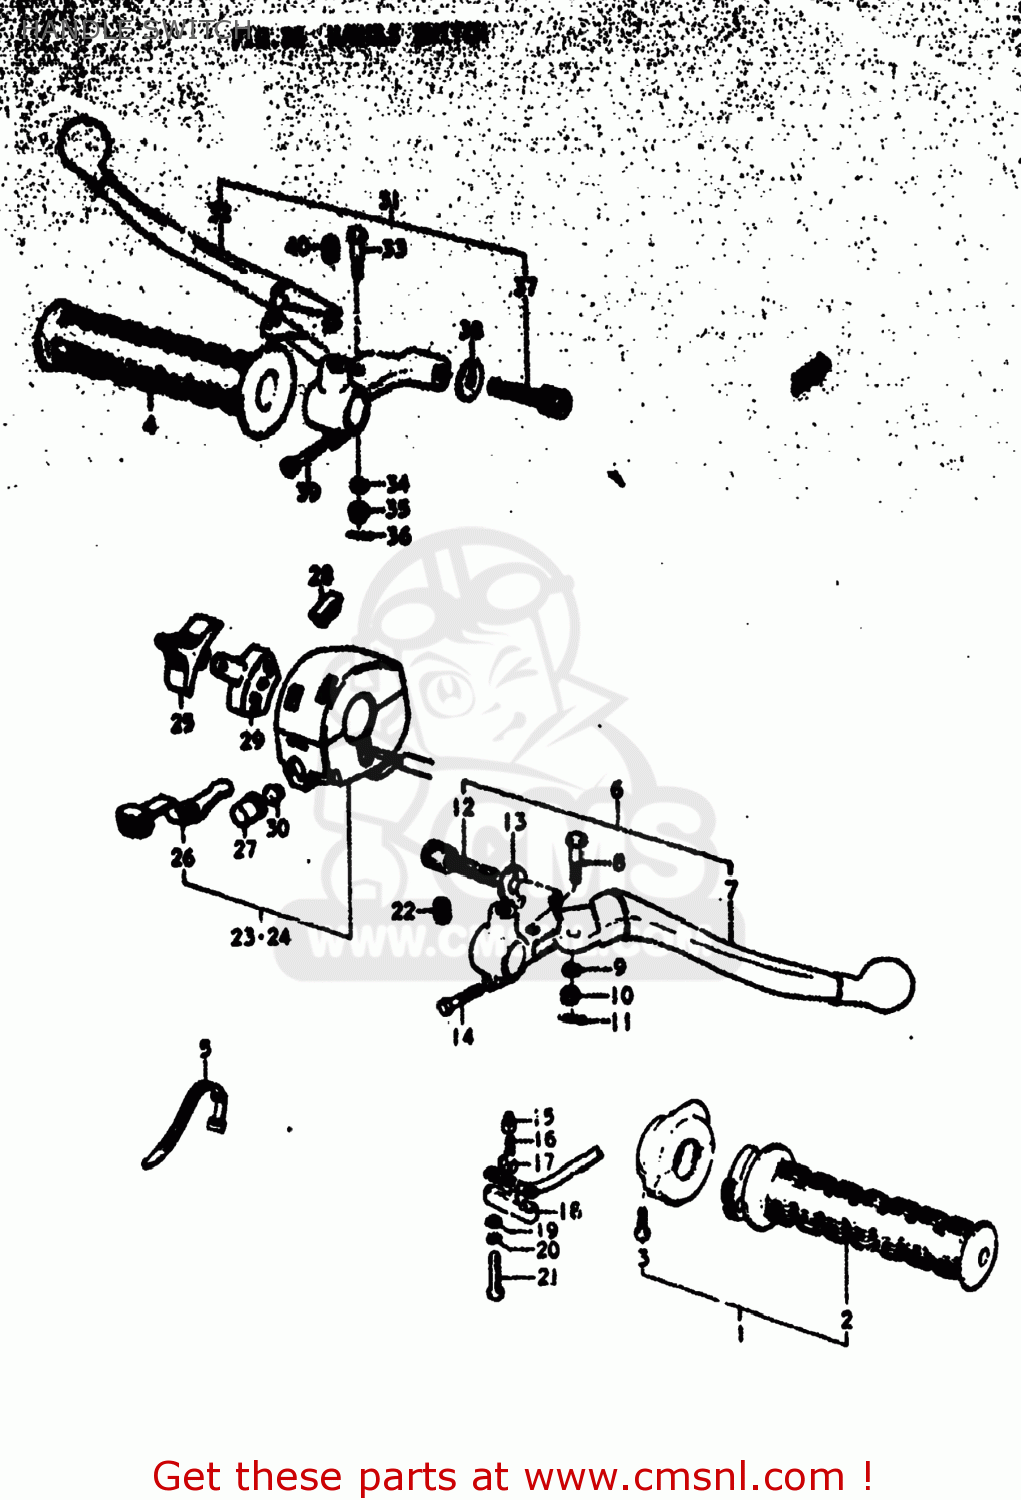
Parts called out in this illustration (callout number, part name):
1	GRIP ASSY,THROTTLE
2	GRIP,THROTTLE
3	SCREW
4	GRIP
5	CLAMP(L:120)
6	LEVER ASSEMBLY,BRAKE
7	LEVER ASSEMBLY,ADJUST
8	BOLT,LEVER
9	LOCK WASHER
10	NUT,LEVER FITTNG
11	COTTER PIN
12	ADJUSTER,CABLE
13	NUT,CABLE ADJUSTER
14	BOLT
15	HOLDER
16	SPRING
17	PLATE
18	COVER,FR BK TERMINAL BASE
19	WASHER
20	LOCK WASHER
21	SCREW
23	SWITCH ASSEMBLY,HANDLE
24	SWITCH ASSEMBLY,HANDLE
25	KNOB,HANDLE SWITCH
26	KNOB,HANDLE SWITCH
27	BUTTON, HORN
29	SLIDING BLOCK, DIMMER SWITCH
30	PLATE,HORN BUTTON
31	LEVER ASSEMBLY
32	LEVER,CLUTCH
33	BOLT,LEVER
34	LOCK WASHER
35	NUT,LEVER FITTNG
36	COTTER PIN
37	ADJUSTER,CABLE
38	NUT,CABLE ADJUSTER
39	BOLT
